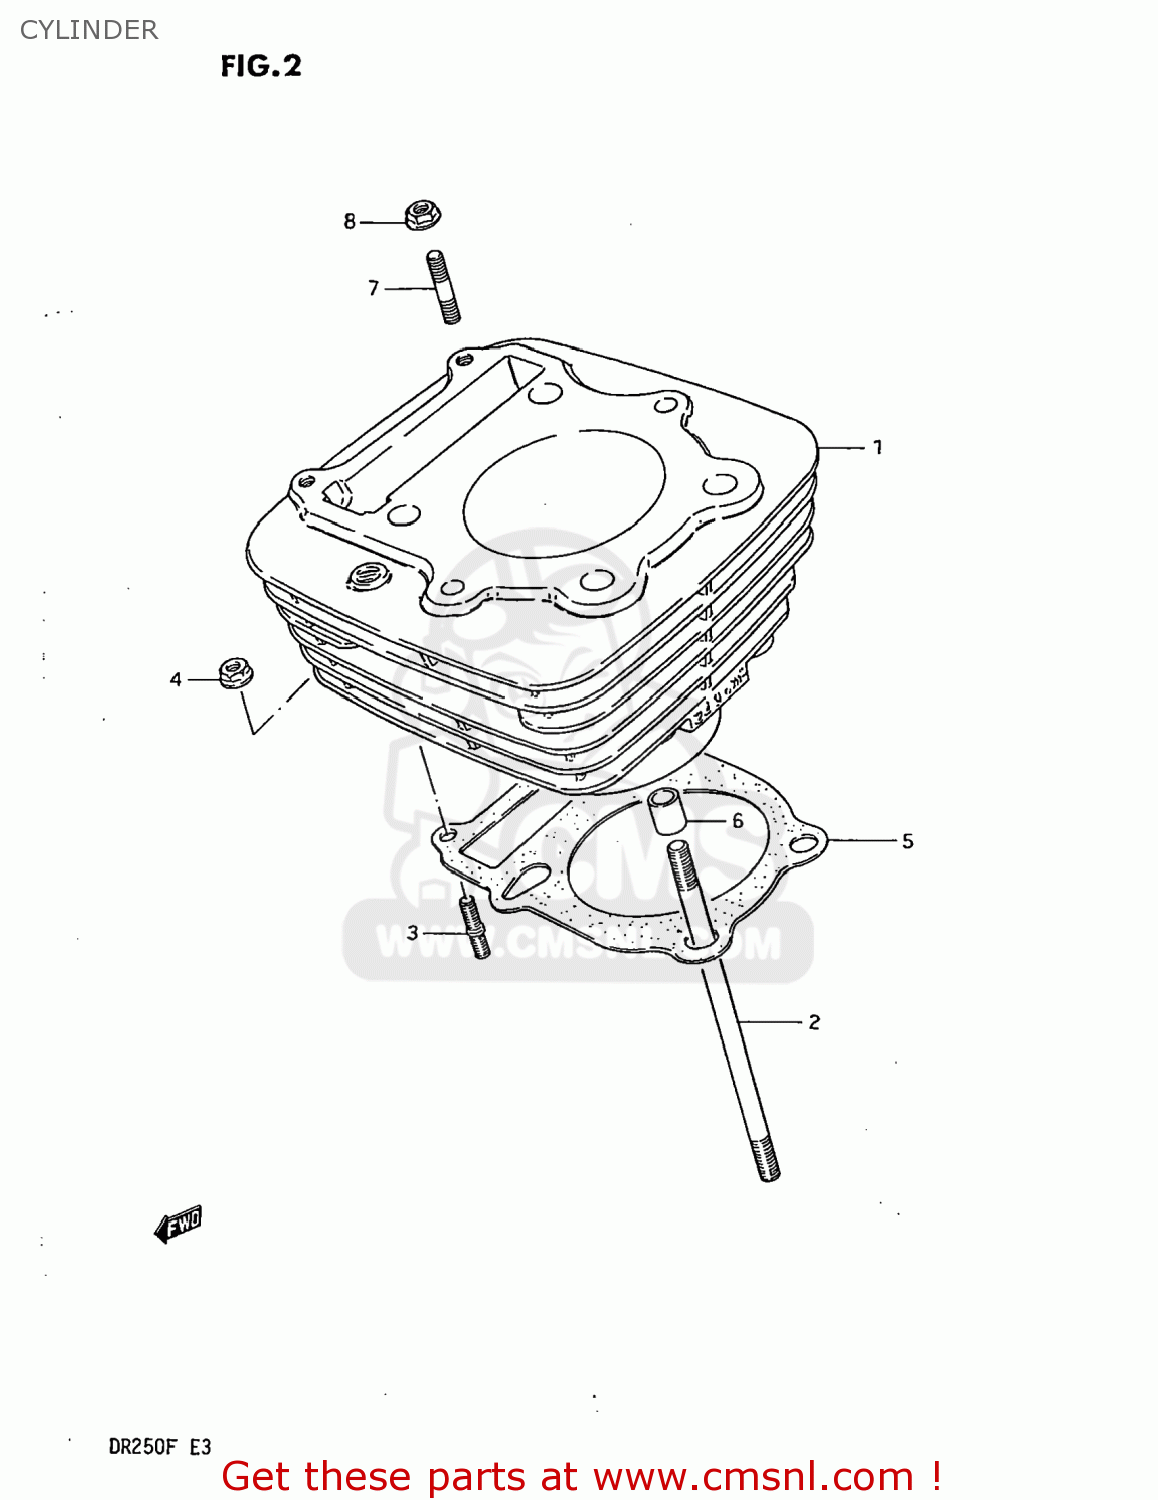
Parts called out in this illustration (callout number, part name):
1	CYLINDER
2	BOLT,STUD
3	STUD 6X25
4	NUT 6MM
5	GASKET,CYLINDER (MCA)
6	PIN
7	BOLT (6X30)
8	NUT 6MM
